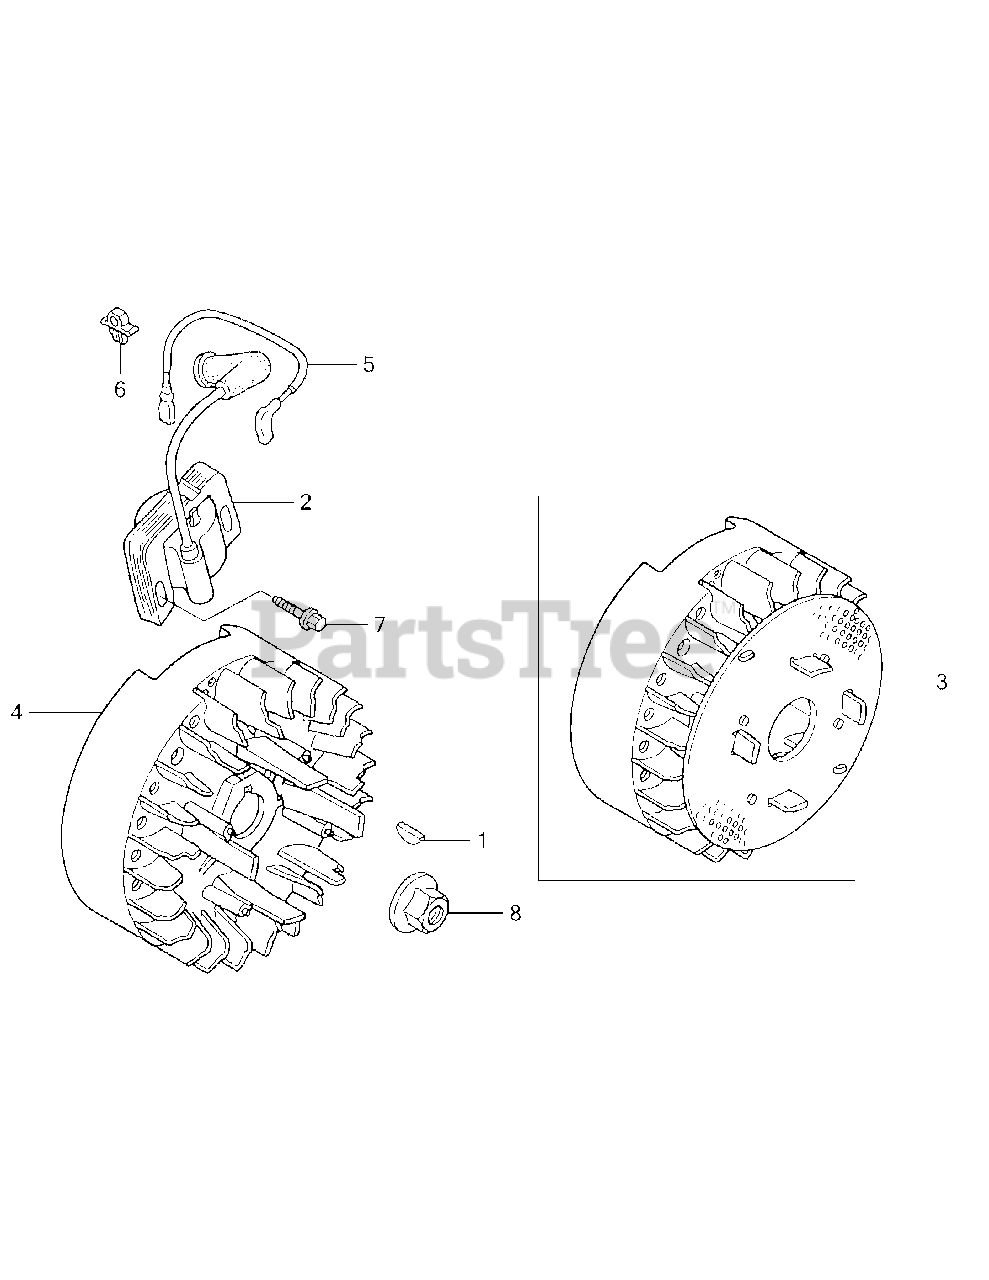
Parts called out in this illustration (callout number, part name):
1	Key, Special Woodruff 25 x 18
2	Coil Assembly, Ignition (Phelon)
4	Flywheel Complete (Phelon)
5	Cord, Stop Switch
6	Holder, Stop Switch Cord
6	Holder, Wire (Fastex)
7	Bolt, Flange 6 x 20 (CT200)
8	Nut, Special 14mm
